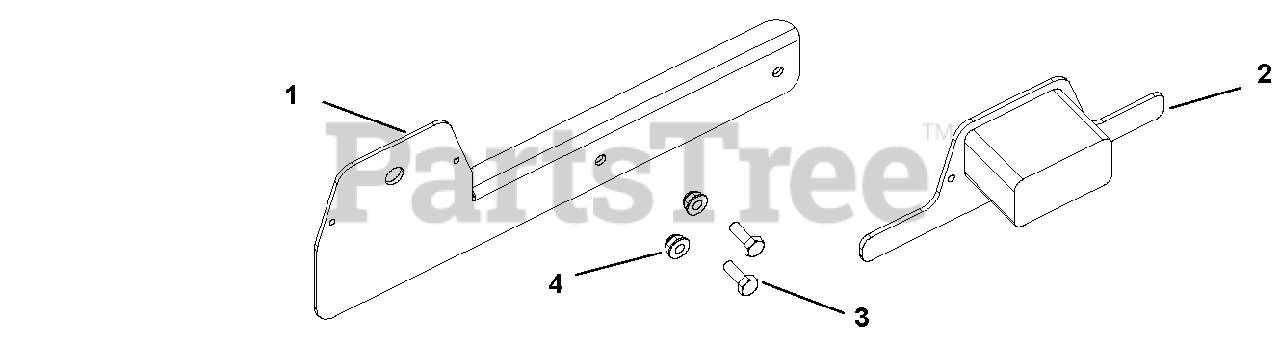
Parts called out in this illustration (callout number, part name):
1	Bracket, License Plate (Ships preassembled with item 2)
2	Light (Ships preassembled with item 1)
3	Bolt, Hex .25-20 x .75
4	Nut, Nyloc Flange .25-20
